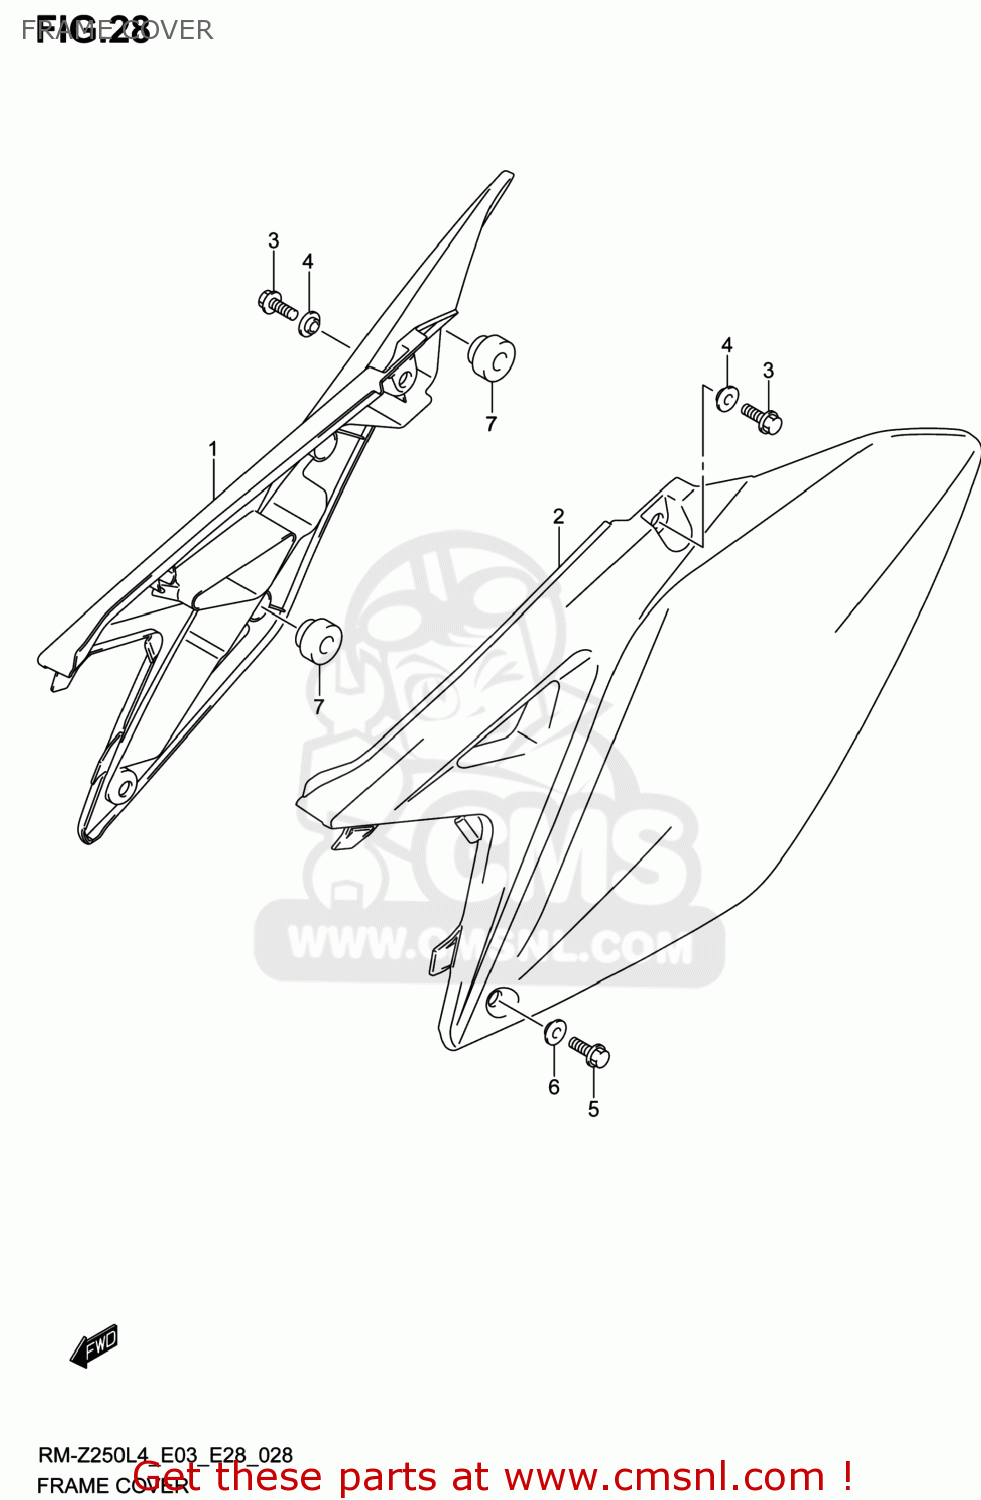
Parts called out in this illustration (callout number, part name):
1	COVER,FRAME R
2	COVER,FRAME L
3	BOLT
4	WASHER,FRAME COVER & SEAT
5	BOLT
6	WASHER,FRAME COVER & SEAT
7	CUSHION
